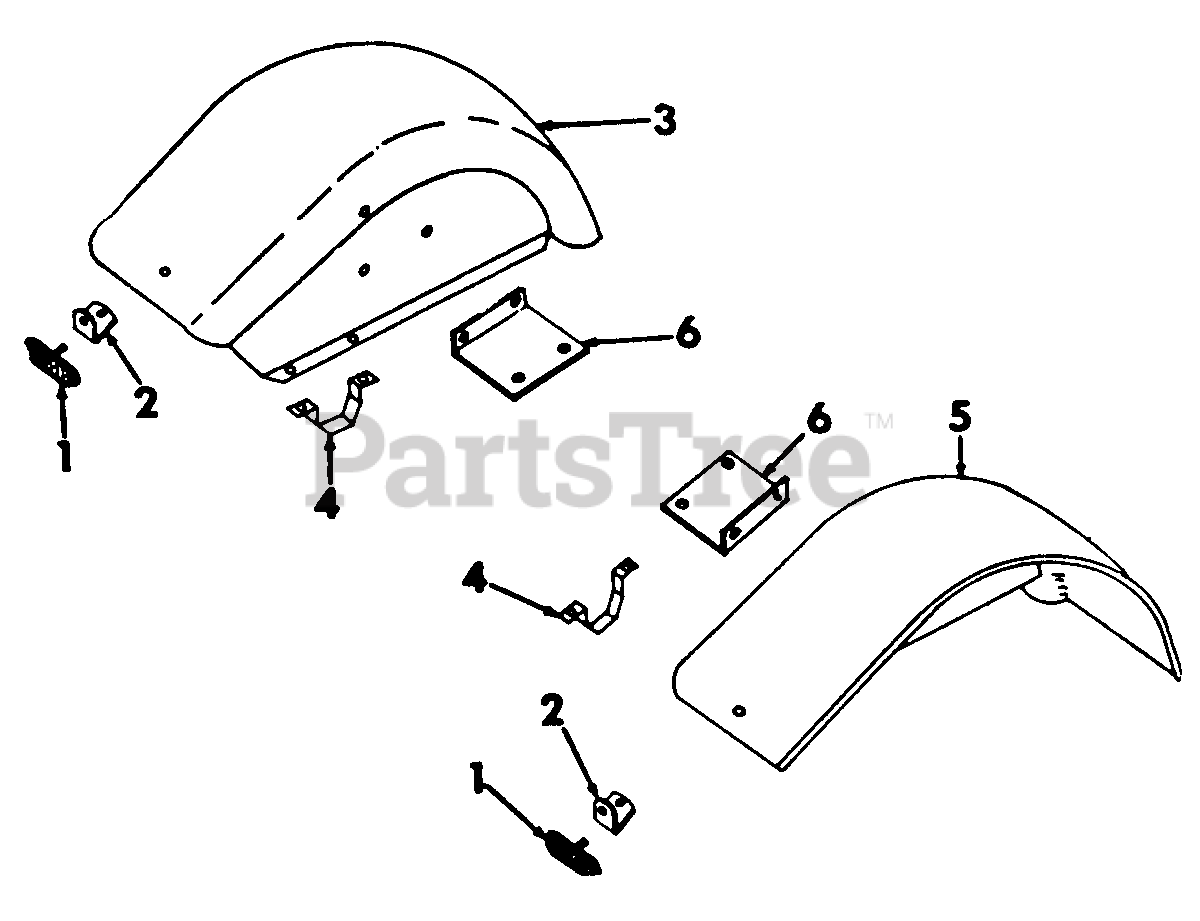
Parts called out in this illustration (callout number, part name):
1	Reflector, Fender
2	Bracket, Reflector
3	Fender Assy, LH
4	Clamp, Fender Mounting
5	Fender Assy, RH
6	Bracket, Fender Frame Mounting
